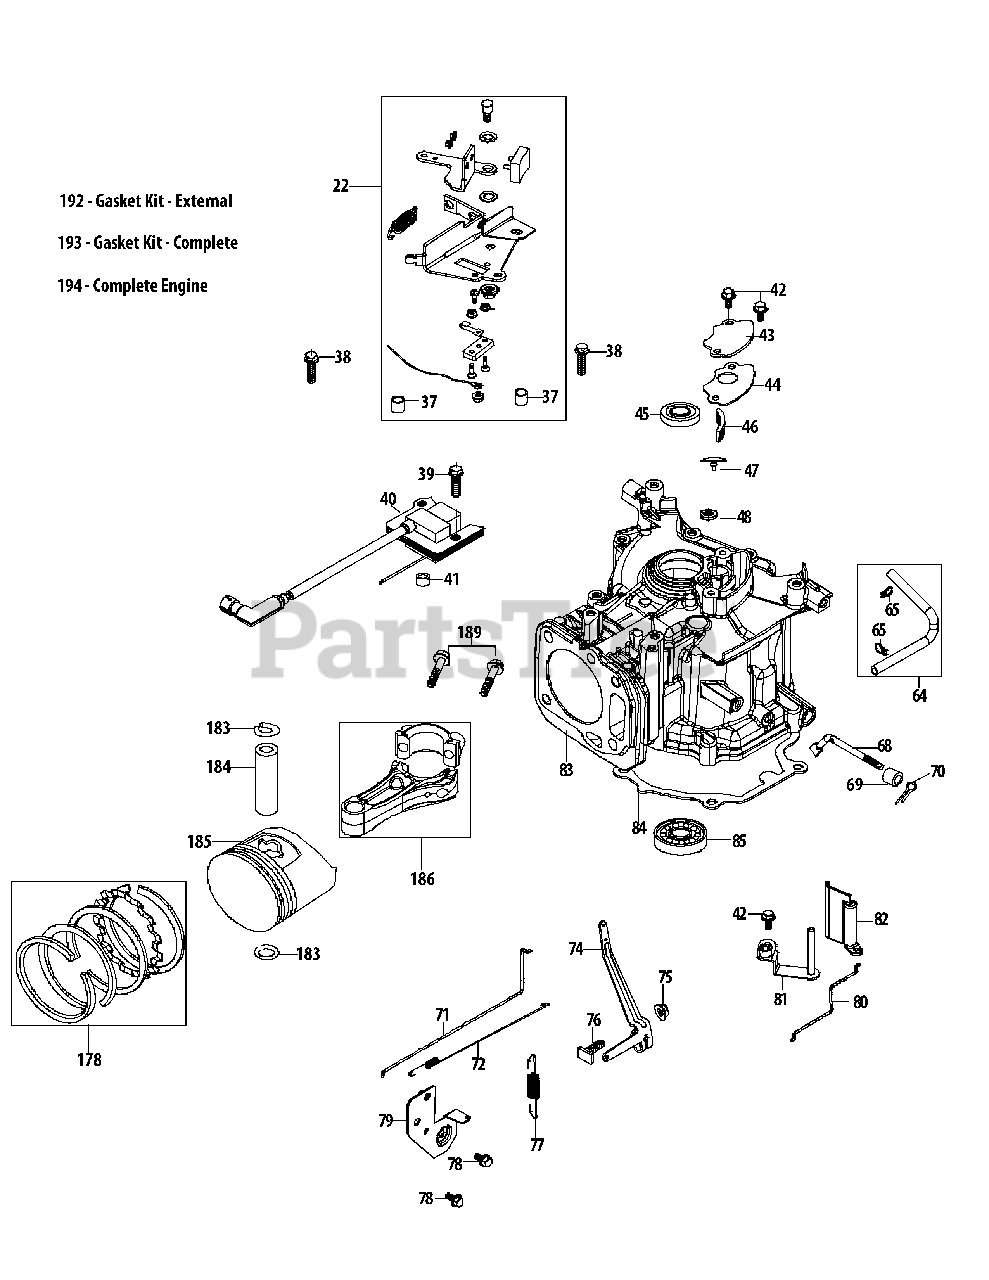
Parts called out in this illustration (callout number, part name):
22	Stop Switch and Brake Ass'y
37	Brake Spacer
38	Bolt M6X35
39	Bolt M6X30
40	Ignition Coil Assembly
41	Ignition Coil Spacer
42	Bolt M6X14
43	Breather Cover Plate
44	Breather Gasket
45	Upper Crankshaft Seal
46	Breather Screen
47	Breather Valve
48	Breather Valve Base
64	Breather Hose Assembly
65	Breather Hose Clamp
68	Governor Arm Shaft
69	Governor Seal
70	Governor Arm Shaft Cotter Pin
71	Throttle Linkage
72	Throttle Linkage Spring
74	Governor Arm
75	Governor Arm Nut M6
76	Governor Arm Bolt
77	Governor Spring
78	Bolt M6X12
79	Component Bracket
80	Choke Linkage
81	Air Vane Bracket
82	Air Vane
83	Shortblock
84	Crankcase Cover Gasket
85	Main Bearing
178	Piston Ring Set
183	Piston Pin Snap Ring
184	Piston Pin
186	Connecting Rod Assembly
189	Connecting Rod Bolt
192	Gasket Kit - External
193	Gasket Kit - Complete
194	Complete Engine
